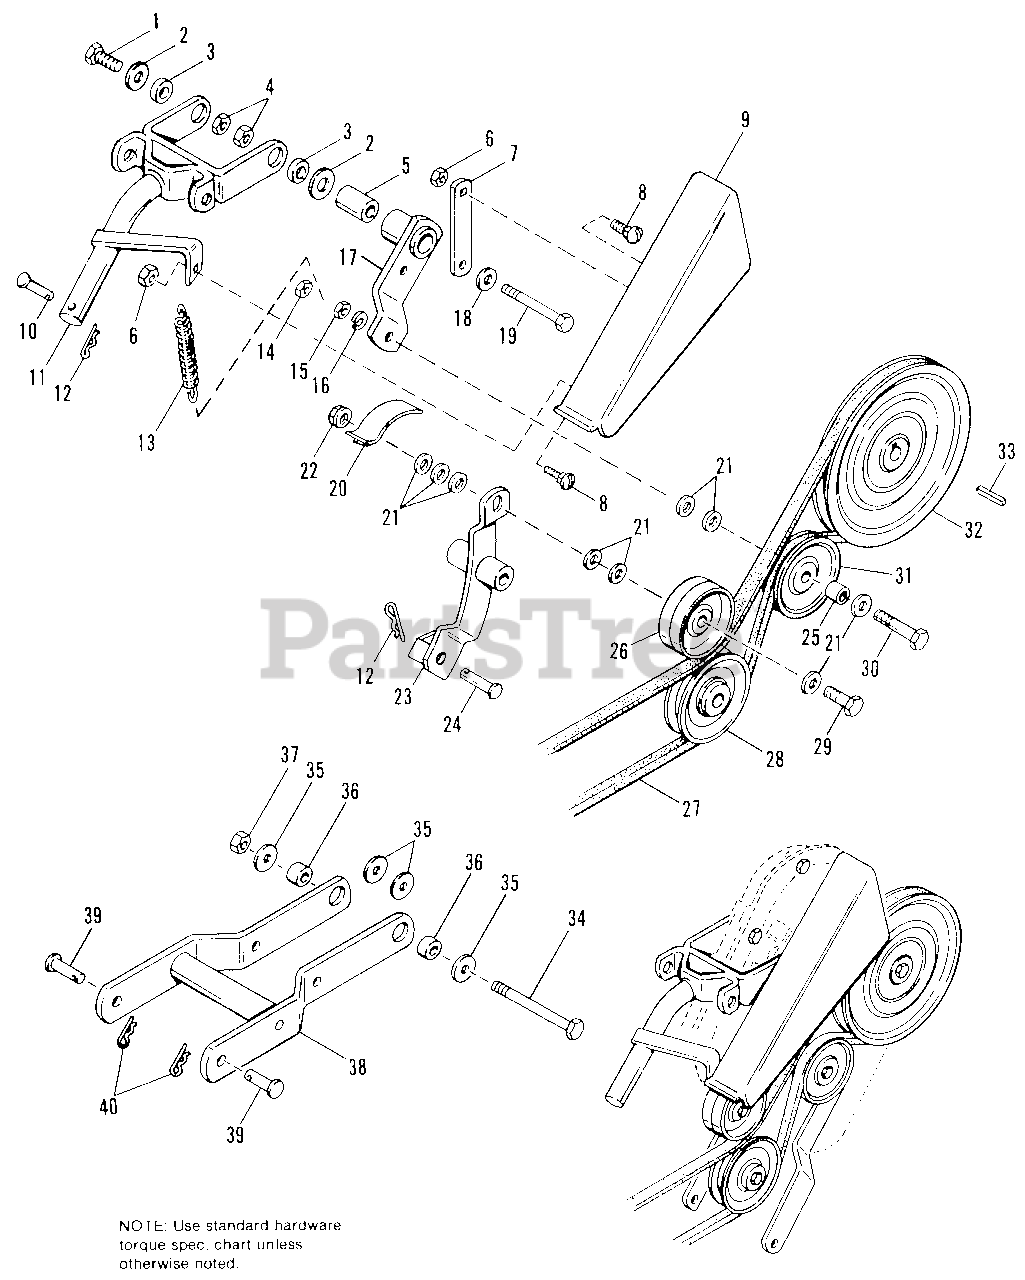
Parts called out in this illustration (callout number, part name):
1	CAPSCREW Hex Hd, 7/16-14 x 1-1/4
2	WASHER, Plain, 3/8
4	LOCKNUT, Flange, 7/16-14
6	LOCKNUT, Whiz, 5/16-18
7	SUPPORT, Rear Belt Guard
8	BOLT, Carriage, 5/16-18 x 3/4
9	GUARD, Belt
10	PIN
11	BAR ASSY, Lift
12	CLIP, Spring (Serviced in 5-pack only)
14	LOCKNUT, 3/8-16
15	NUT, Hex, Full, 3/8-16
16	LOCKWASHER, 3/8
17	LEVER ASSY, Clutch
18	WASHER, Plain, 7/16
19	CAPSCREW, Hex Hd, 7/16-14 x 3-1/2
21	WASHER, Plain, 5/16
22	NUT, Flange, Whizlock 3/8-16
23	ARM ASSY, Idler
26	PULLEY, Idler
27	BELT "V", Drive
28	PULLEY, Idler
29	CAPSCREW, Hex Hd, 3/8-16 x 2
30	CAPSCREW, Hex Hd, 3/8-16 x 3
31	PULLEY ASSY
34	CAPSCREW, Hex Hd, 1/2-13 x 5
35	WASHER, Plain, 1/2
37	LOCKNUT, Hex, 1/2-13
40	CLIP, Spring (Serviced in 5-pack only)
40	ARM SUB ASSY, Idler (Includes Ref Nos. 20, 21, 22, 23, 26, 27, 28 & 29)
